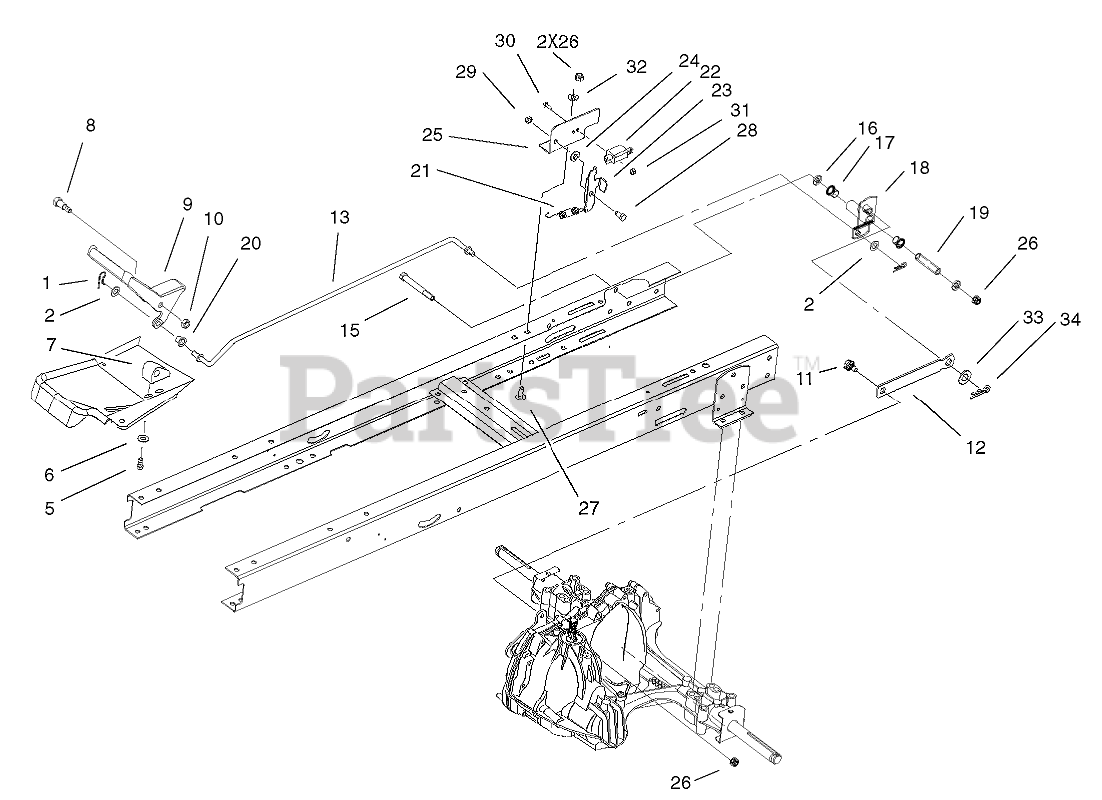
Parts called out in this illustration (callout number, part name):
1	PIN-COTTER
2	WASHER-FLAT
5	SCREW-PLASTITE
6	WASHER-FLAT
7	BLOCK-PIVOT
8	SCREW-SHOULDER, HH
9	PEDAL-CONTROL, SPEED
10	NUT-LOCK, NI
11	BOLT-SHOULDER
12	LINK-CONTROL, SPEED
13	ROD-CONTROL, SPEED
15	SCREW-HH
16	WASHER-FLAT
17	BUSHING-NYLINER
18	PIVOT ASM
19	SPACER-PIVOT
20	BUSHING-FLANGED
21	SPRING-EXTENSION
22	SWITCH-POLE, SINGLE
23	BRACKET-PIVOT
24	WASHER-STEPPED
25	BRACKET-ADJUSTMENT
26	NUT-LOCK, NI
27	SCREW-CARR
28	SCREW-HHF
29	NUT-LOCK, NI
30	SCREW-SHH
31	NUT-LOCK
32	WASHER-PLAIN
33	WASHER-FLAT
34	PIN-HAIR
